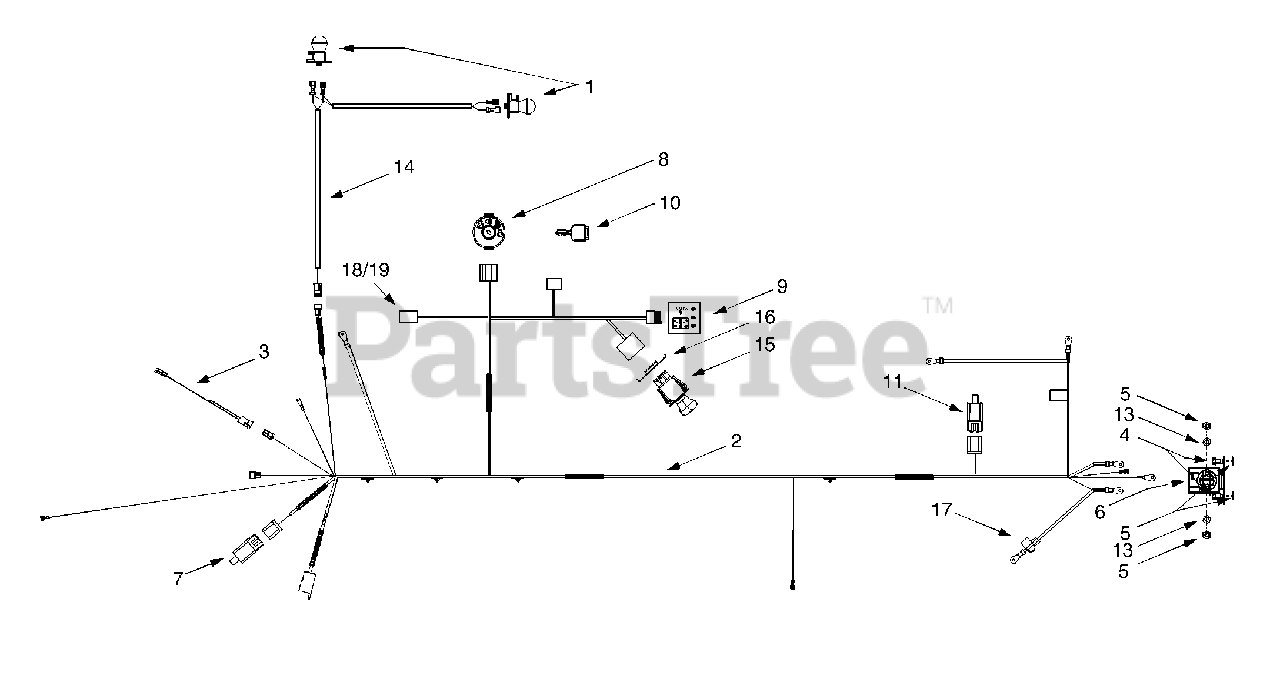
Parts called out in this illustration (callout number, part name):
1	Bulb/Socket Headlight Assembly
2	Wiring Harness w/o Ref. 14
3	Harness Adapter, #18 x 5
4	Self Tapping Screw, 1/4-20 x .5
5	Hex Nut, 1/4-20
6	Solenoid, 12-volt, 100 Amp
7	Snap Mount Safety Interlock Switch (Brake)
8	Ignition Switch
9	Indicator Monitor / Ammeter
10	Ignition Key
11	Safety Plunger Switch (Seat)
13	Lock Washer, 1/4
14	Headlight Harness
15	Electric PTO Switch
16	Retainer Bracket
17	Positive Terminal Cover (Boot)
18	Fuse Holder
19	20-amp Fuse
